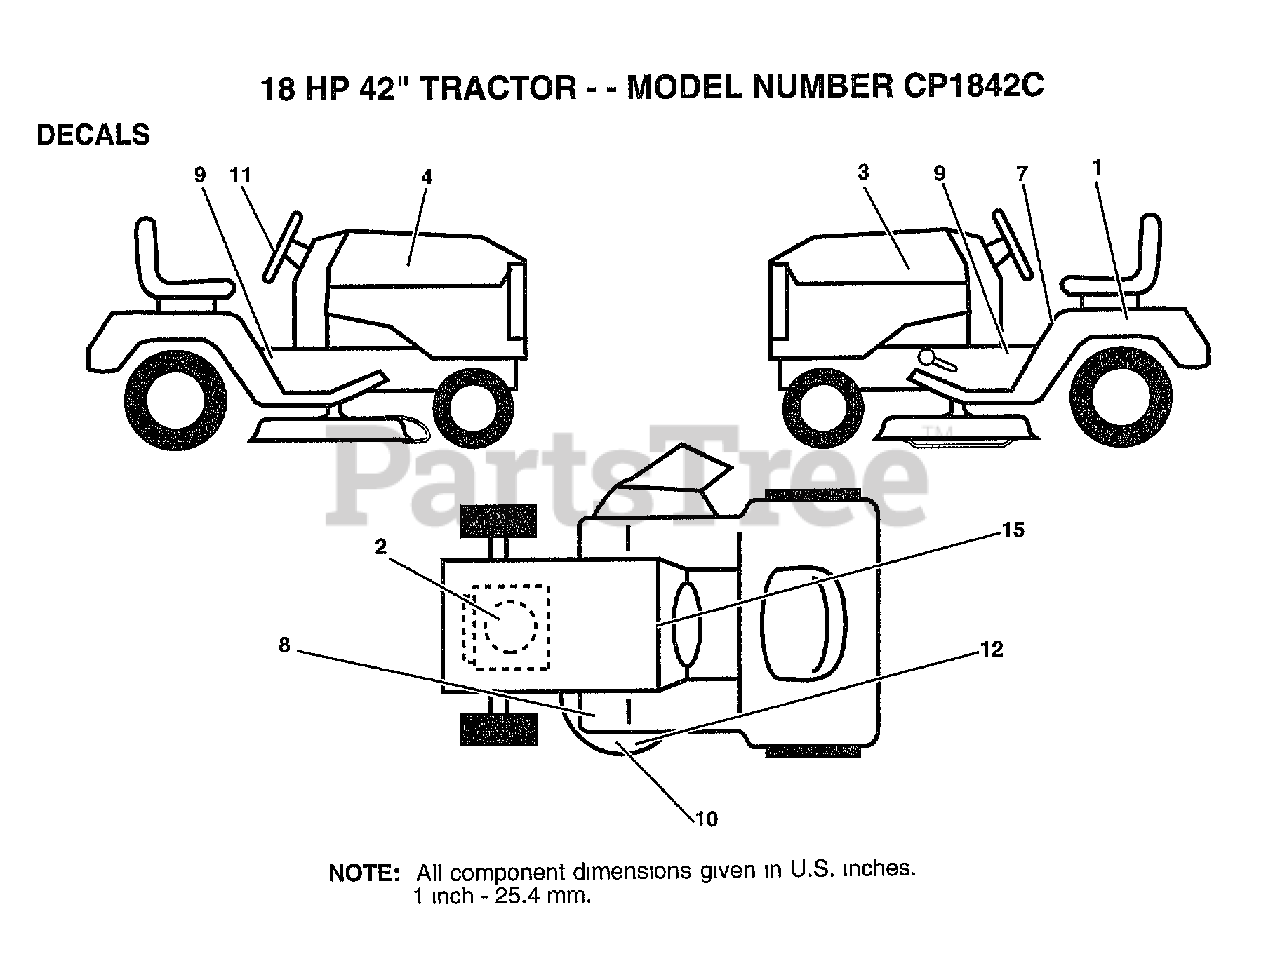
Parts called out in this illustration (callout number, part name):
1	DECAL.FEND.QUICK.
2	DECAL.ENG.272757
4	DECAL HOOD STRIPE RH
7	DECAL
9	CHASSIS DECAL
10	DECAL MWR QC SYS
11	DECAL.WHL.STRG.
15	DECAL.DASH.INST.
